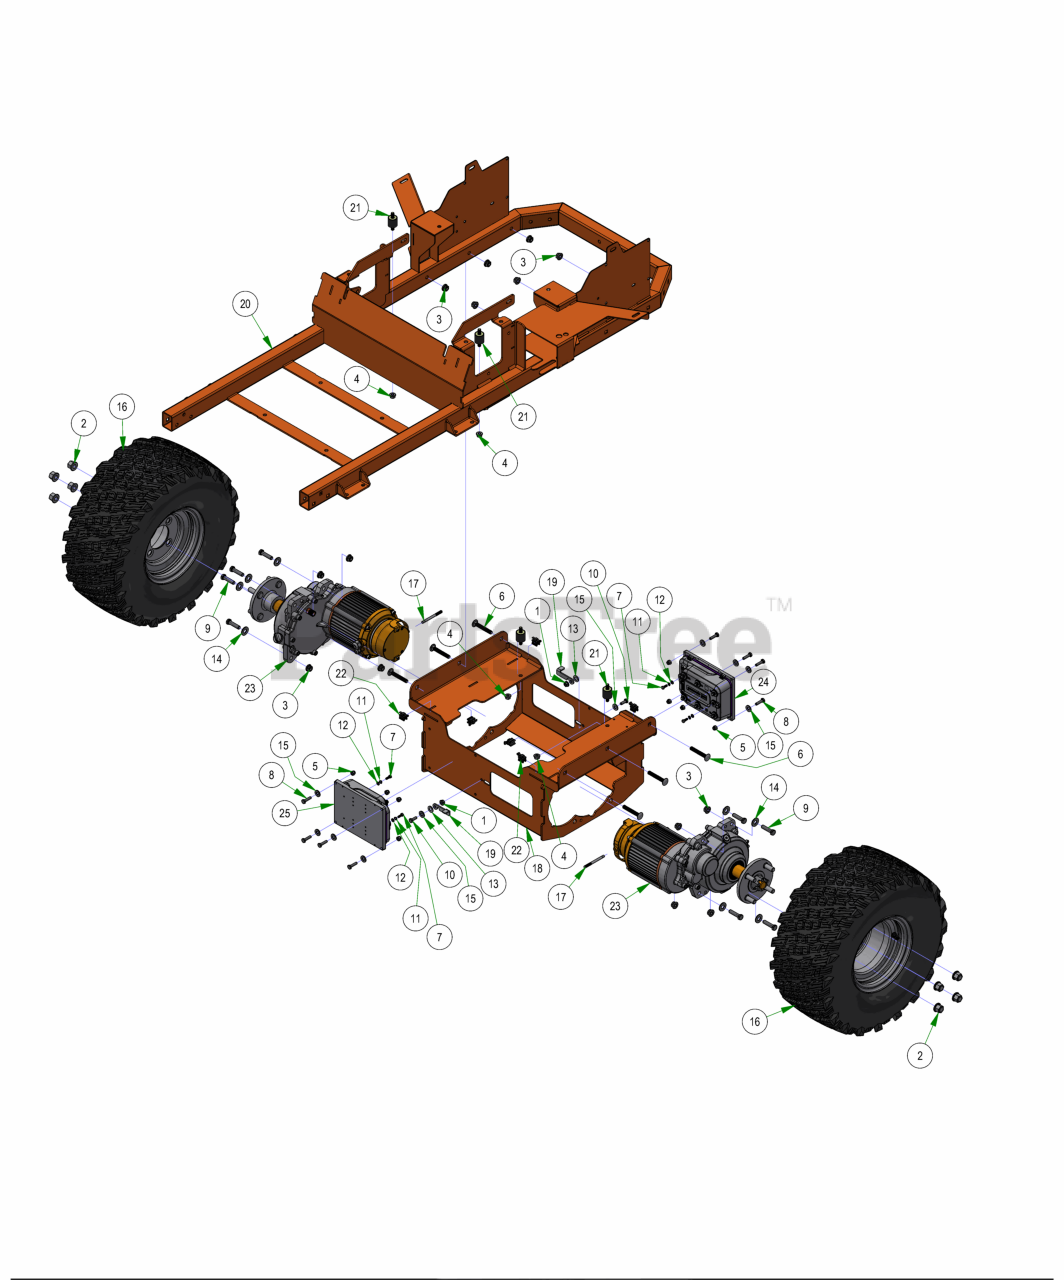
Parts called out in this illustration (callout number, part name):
1	1/4-20 NYL INSERT FLANGE LOCKNUT ZINC
2	Acorn Lug Nut
3	3/8-16 NYLON INSERT FLANGE LOCKNUT (GR.F) ZINC
4	5/16-18 NYLON INSERT FLANGE LOCKNUT ZINC
5	1/4-20 NYLON INSERT LOCKNUT ZINC
6	3/8" x 2 1/2" Carriage Bolt
7	M5 x 0.8mm x 14mm 8.8 hex head screw
8	1/4-20 X 1 HEX CAP SCREW (GR.5) ZINC
9	3/8-16 X 1-1/2 HEX CAP SCREW (GR.5) ZINC
10	1/4-20 X 3/4 HEX CAP SCREW (GR.5) ZINC
11	M5 Split Lock Washer
12	M5 Flat Washer
13	.390 ID X .750 OD X .062 THK FLAT WASHER NYLON
14	3/8 FLAT WASHER USS (1" OD) ZINC
15	1/4 USS FLAT WASHER (3/4 OD) ZINC
16	20 x 10-8 Reaper Assy.
17	2023 Residential Electric Mower Neutral Lever
18	Residential E Mower Undercarage
19	Residential E Mower Neutral Lever
20	Residential E Mower Frame
21	Vibration-Damping Sandwich Mount
22	Edge Clip With Ziptie
23	Residential E Mower Drive Motor
24	Controller of Drive Motor
25	Controller of Blade Motor
